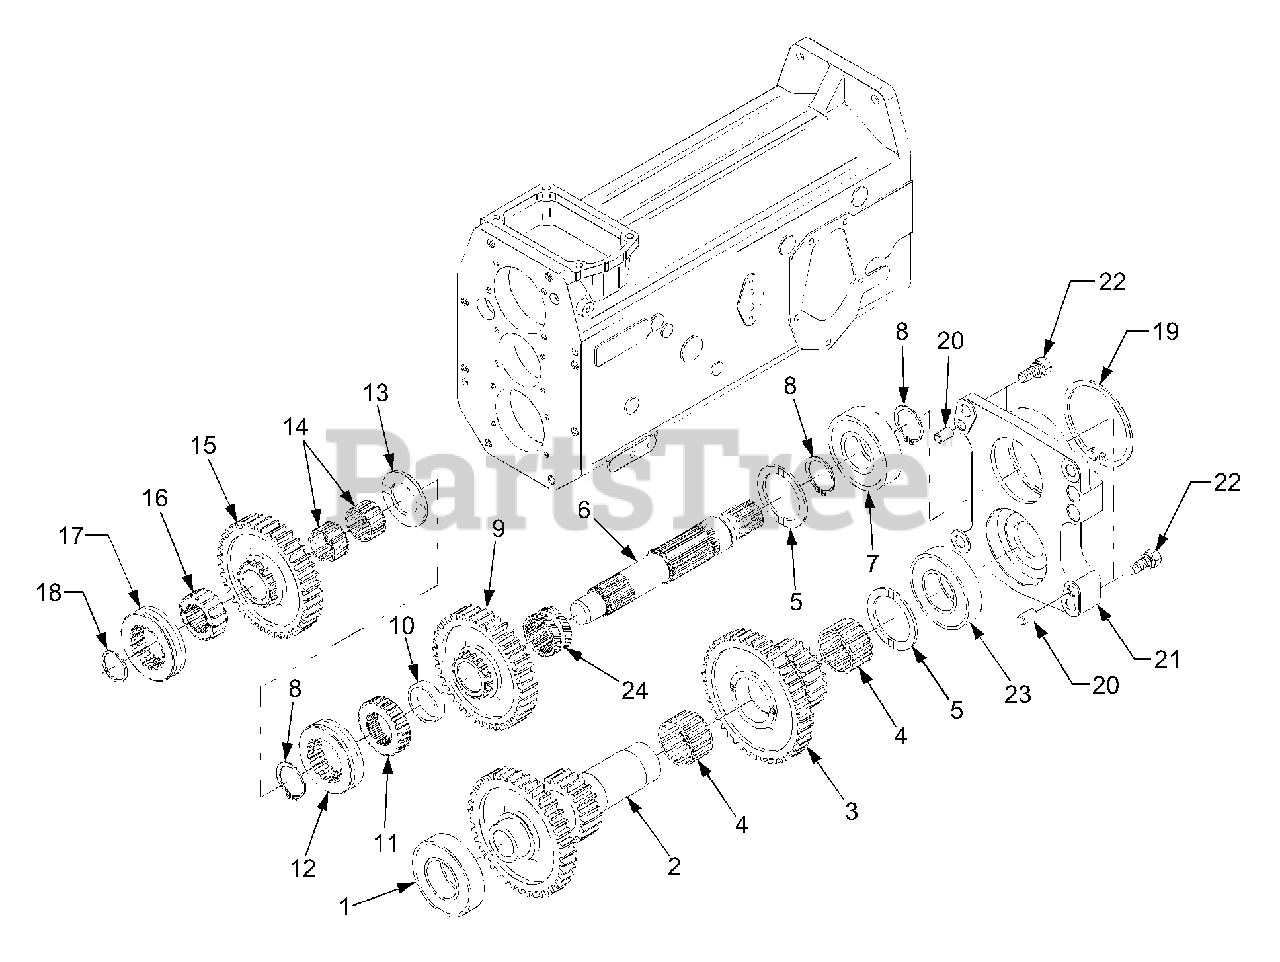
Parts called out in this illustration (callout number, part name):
1	Bearing, Ball
4	Bearing, Needle
5	Collar, Thrust
6	Shaft, Hi-low Shift
7	Bearing, Ball
13	Collar, Thrust
14	Bearing, Needle
20	Pin, Straight
21	Case, Bearing
23	Bearing, Ball
